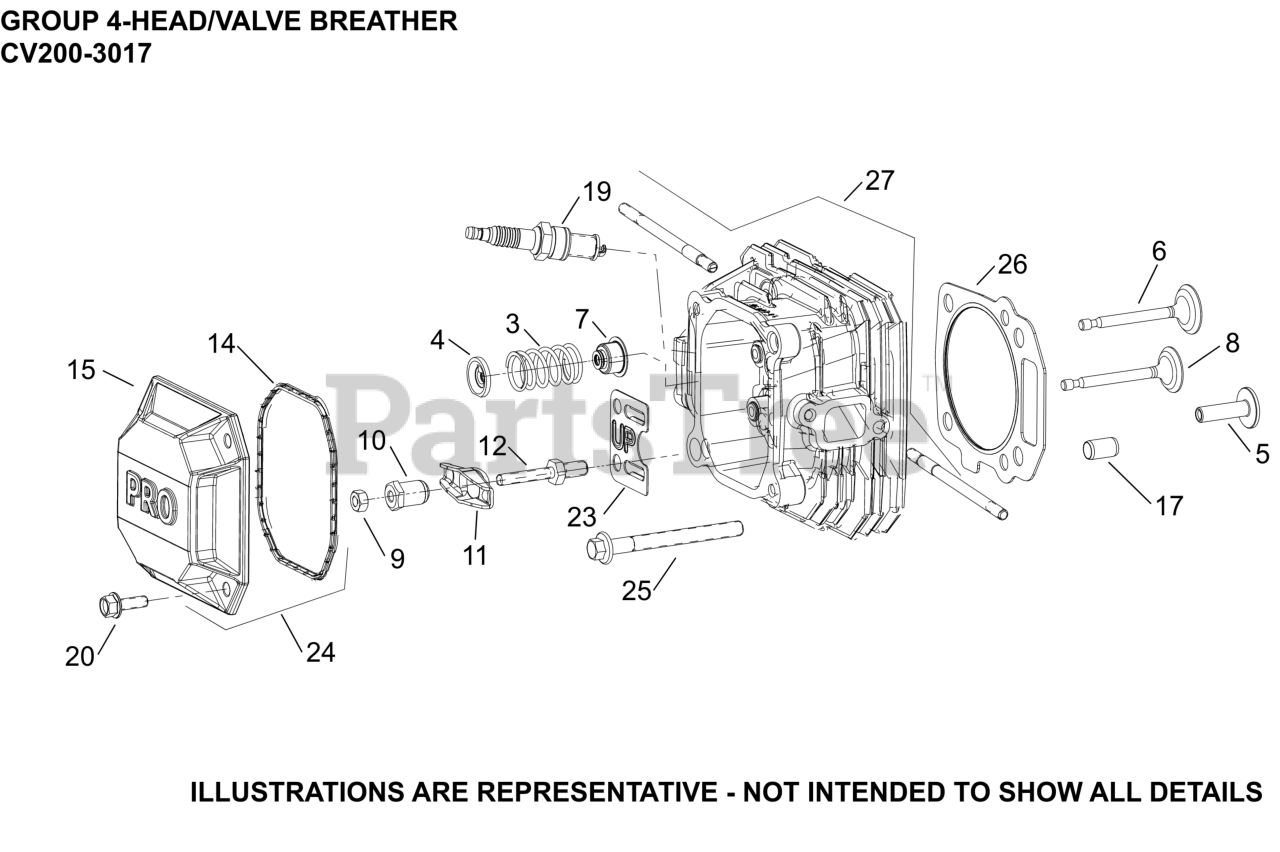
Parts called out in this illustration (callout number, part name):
3	SPRING, VALVE
4	RETAINER, VALVE SPRING
5	LIFTER, VALVE
6	VALVE, INTAKE
7	SEAL, VALVE
8	VALVE, EXHAUST
9	NUT, HEX JAM
10	PIVOT, ROCKER ARM
11	ARM, ROCKER
12	STUD, ROCKER ARM
14	SEAL, VALVE COVER
15	COVER, VALVE-USE 14 096 184-S
17	DOWEL, CYLINDER HEAD
19	PLUG, SPARK 12MM RFI
20	SCREW, HEX FLANGE (M6)
23	PLATE, PUSHROD GUIDE
24	COVER, VALVE ASSEMBLY
25	SCREW, HEX FLANGE (M8)
26	KIT, HEAD GASKET
27	KIT, CYLINDER HEAD-USE 14 818 01-S
NI	ROD, PUSH
